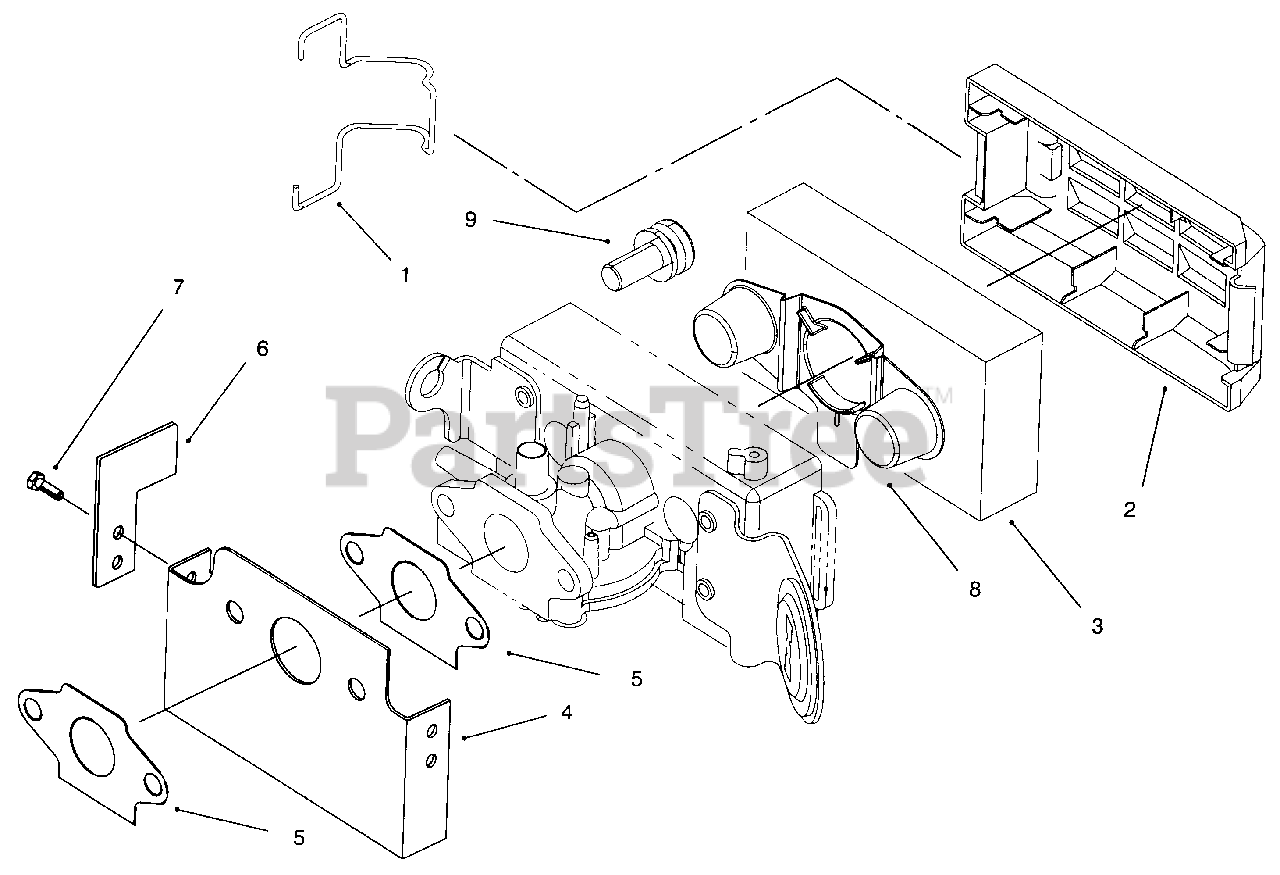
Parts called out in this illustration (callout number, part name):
1	Retainer-Cover
2	Cover-Air Filter
3	Element-Air Filter
4	Shield-Carburetor (Int'l)
5	Gasket-Carb.
6	Shield-Governor F (Int'l)
8	Shield-Fuel
